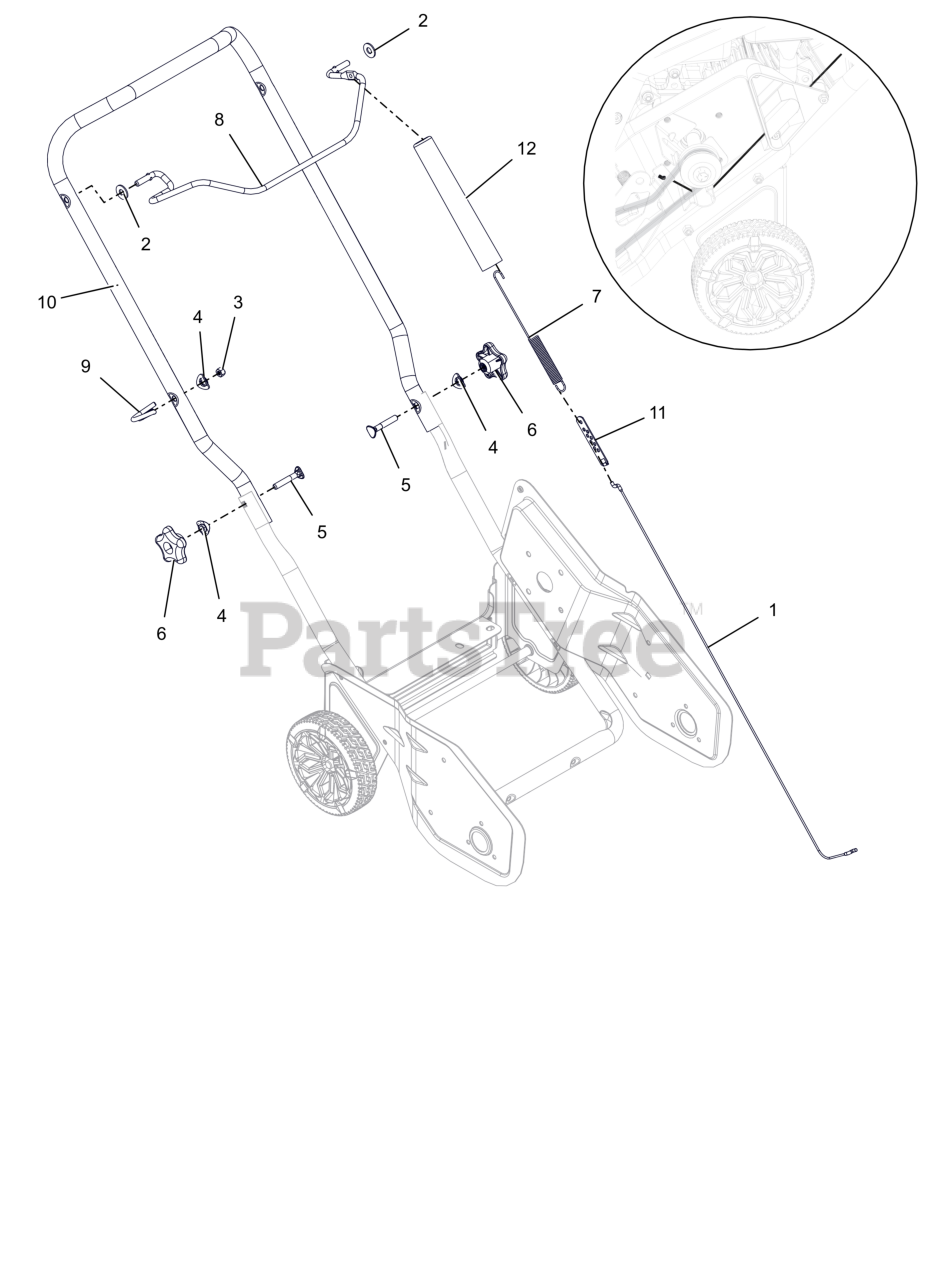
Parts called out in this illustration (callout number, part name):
1	CABLE, AUGER
2	WSHR, FLAT .375X.875X.065 (BLACK)
3	NUT, NYLON .250 - 20 (BLACK)
4	WSHR, HANDLEBAR - 5/16
5	.312-18 X 2 HANDLE BAR SCREW
6	.321-18 KNOB
7	SPRG, OPC
8	HANDLE, BAIL
9	GUIDE, RECOIL ROPE
10	KIT, UPPER HANDLEBAR W/DECAL
11	ADJUSTER, OPC
12	COVER, OPC SPRING
